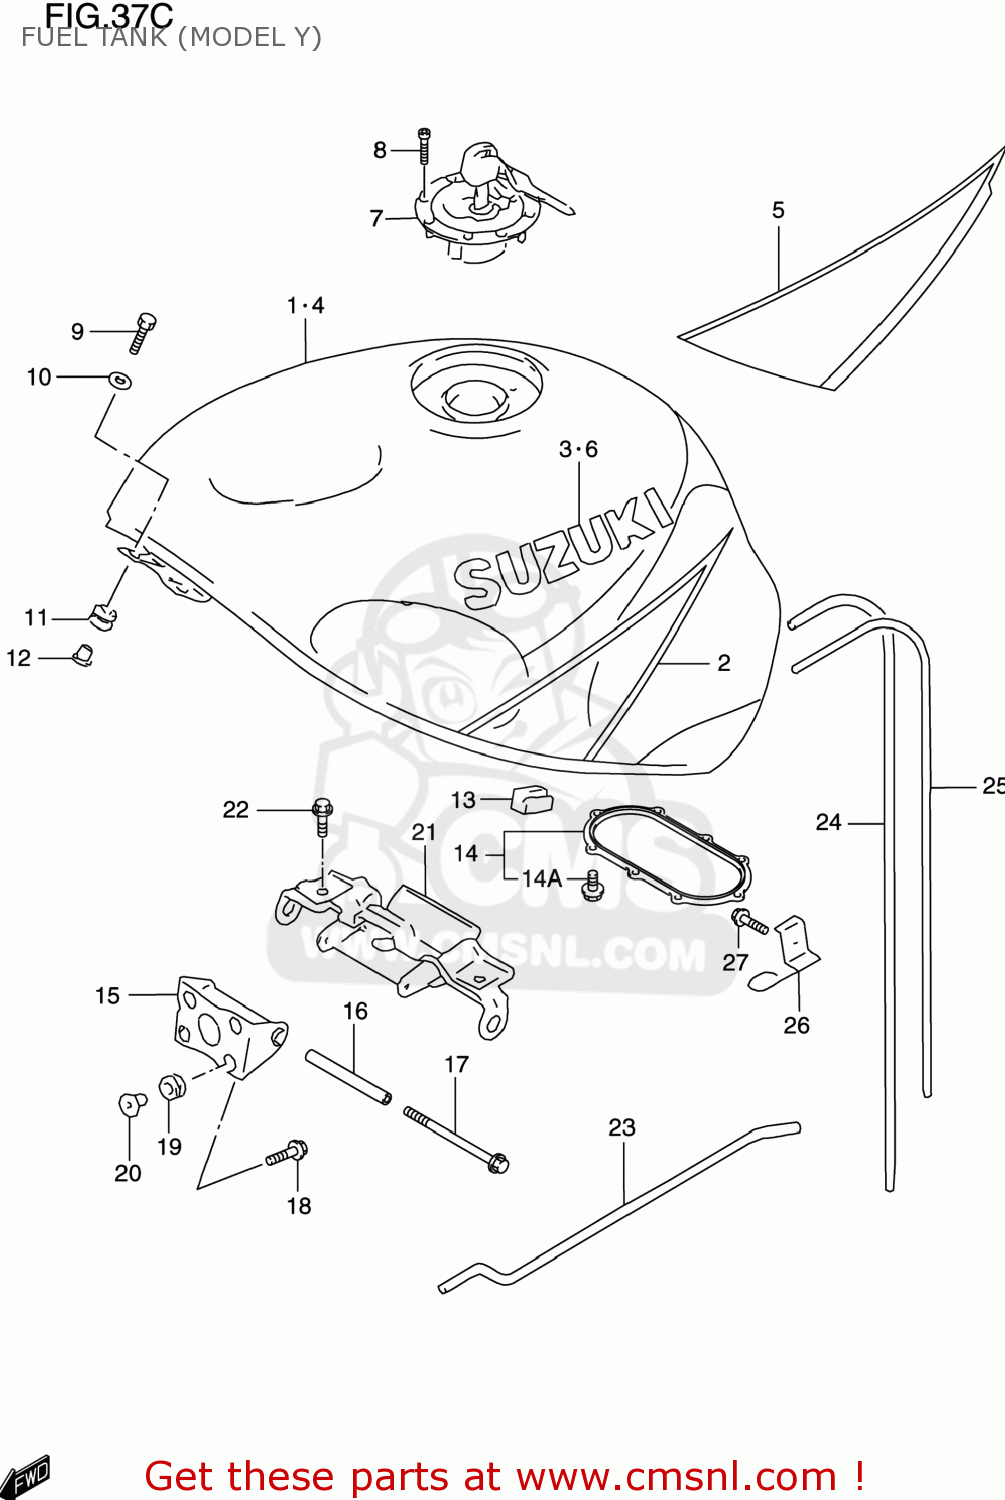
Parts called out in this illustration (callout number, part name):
1	TANK ASSY,FUEL
2	TAPE SET,FUEL TANK
3	EMBLEM,FUEL TANK
4	TANK ASSEMBLY,FUEL
5	TAPE SET,FUEL TANK
6	EMBLEM,FUEL TANK
7	CAP SET,FUEL TANK
8	BOLT(5X20)
9	SCREW(6X25)
10	WASHER(6.5X18X1.6)
11	CUSHION
12	WASHER
13	CUSHION,FUEL TANK SIDE
14	PACKING SET,FUEL PUMP (NAS)
14A	BOLT,FUEL PUMP
15	BRACKET COMP,FUEL TANK
16	SPACER,FUEL TANK RR
17	BOLT
18	BOLT(6X20)
19	CUSHION
20	WASHER
21	BRACKET,FUEL TANK NO.2
22	BOLT
23	STAY,FUEL TANK
24	HOSE(5X8.2X600)
25	HOSE(7X10.2X600)
26	GUIDE COMP,DRAIN HOSE
27	BOLT
